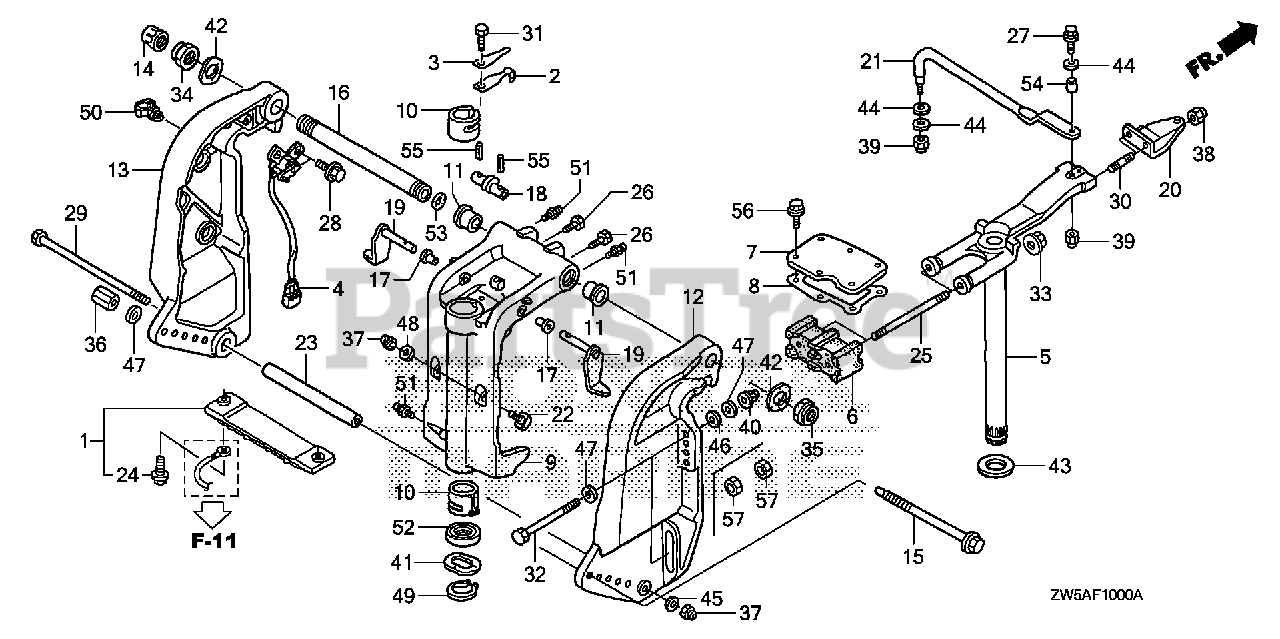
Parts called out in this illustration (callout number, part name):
1	METAL KIT, ANODE
2	SPRING, CLICK
3	SPRING, CLICK ASSIST
4	SENSOR ASSY., TRIM ANGLE
5	FRAME, MOUNTING
6	MOUNT, RUBBER (UPPER)
7	HOLDER, MOUNTING (UPPER)
8	GASKET, MOUNTING HOLDER (UPPER)
9	CASE, SWIVEL *NH282MU* (OYSTER SILVER METALLIC-U)
10	LINER, SWIVEL CASE
11	BUSH, SWIVEL CASE
12	BRACKET, R. STERN *NH282MU* (OYSTER SILVER METALLIC-U)
13	BRACKET, L. STERN *NH282MU* (OYSTER SILVER METALLIC-U)
14	CAP, TILTING BOLT
15	ROD, ADJUSTING
16	SHAFT, TILTING
17	BUSH, TILT ARM
18	BRACKET, TILTING
19	STOPPER, TILT
20	PLATE, STEERING
21	ROD, STEERING
22	RECEIVER, THRUST
23	COLLAR, CYLINDER (LOWER)
24	BOLT, FLANGE (6X23)
25	BOLT, STUD (12X150)
26	BOLT (1/4-28UNF)
27	BOLT (3/8-24UNF)
28	BOLT, FLANGE (6X20)
29	BOLT, HEX. (10X235)
30	BOLT, STUD (10X28)
31	BOLT, HEX. (6X14)
32	BOLT, HEX. (12X119)
33	NUT, FLANGE (12MM)
34	NUT, SELF-LOCK (7/8-14UNF)
35	NUT, SELF-LOCK (25X2.0)
36	NUT, ADJUSTER ROD
37	NUT, SELF-LOCK (10MM)
38	NUT, SELF-LOCK (10MM)
39	NUT, SELF-LOCK (3/8-24UNF)
40	NUT, SELF-LOCK (12MM)
41	WASHER, WAVE (40MM)
42	WASHER, WAVE (26MM)
43	WASHER, THRUST (34MM)
44	WASHER (10MM)
45	WASHER, PLAIN (10MM)
46	WASHER, PLAIN (12MM)
47	WASHER, PLAIN (12MM)
48	WASHER, PLAIN (10MM)
49	CIRCLIP, OUTER (39MM)
50	CLIP, WIRE HARNESS
51	NIPPLE, GREASE
52	OIL SEAL (39.5X52X6) (ARAI)
53	O-RING (15.54X2.62)
54	COLLAR, STEERING ROD
55	PIN, SPRING (2.5X20)
56	BOLT, FLANGE (8X35)
57	NUT, HEX. (12MM)
